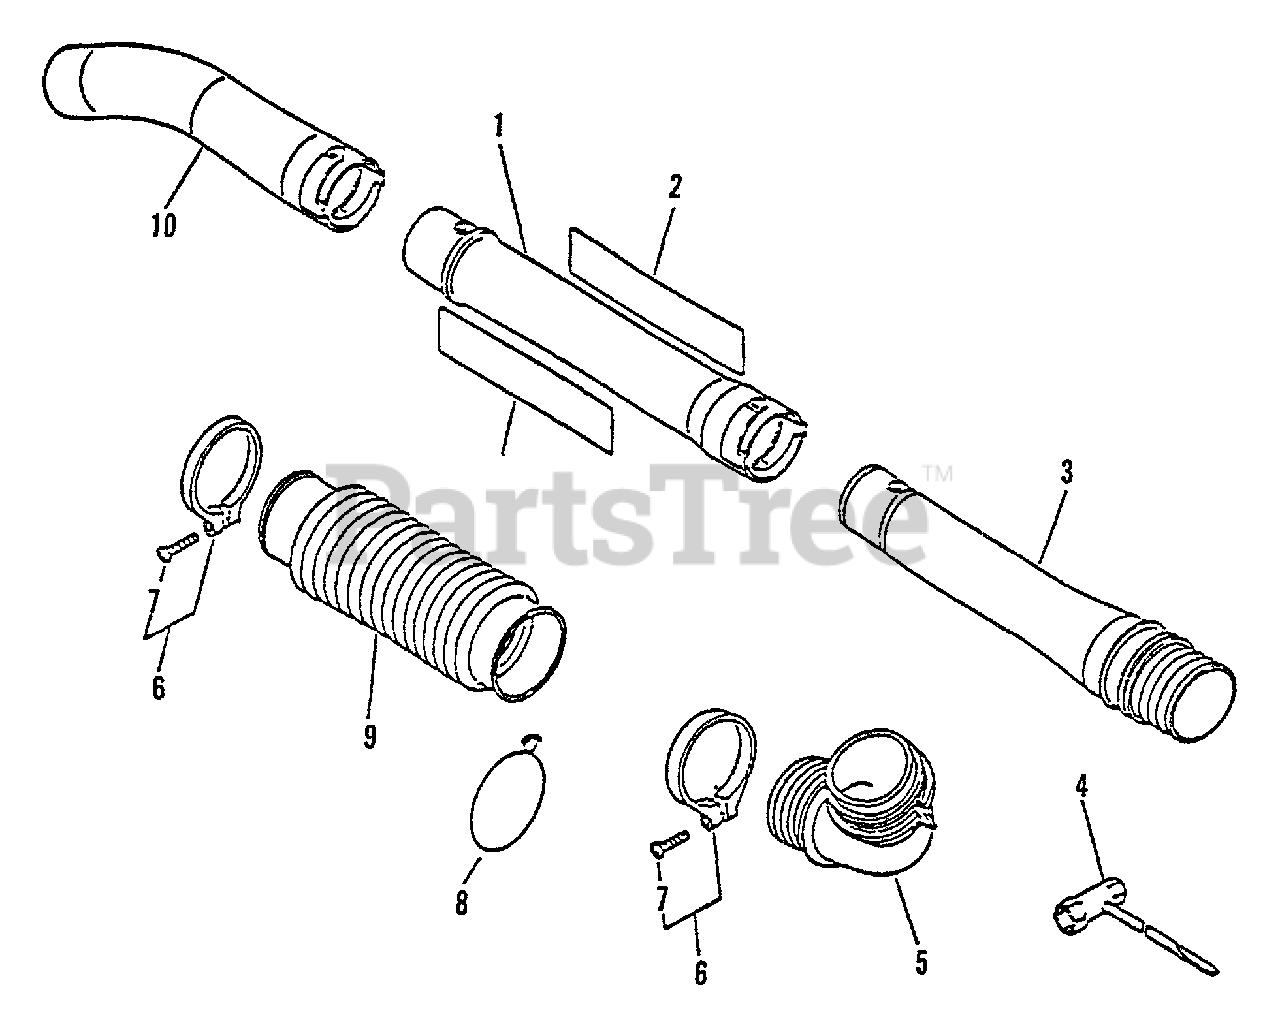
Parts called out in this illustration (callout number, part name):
1	TUBE, BLOWER - STRAIGHT
2	LABEL - LESCO
3	TUBE, BLOWER - SWIVEL
4	T-WRENCH - 10X19mm
5	TUBE, BLOWER - ELBOW
6	CLAMP KIT
7	SCREW - 5X25
8	TIE, CABLE - LARGE
9	TUBE, BLOWER - FLEXIBLE
10	TUBE, BLOWER - CURVED
